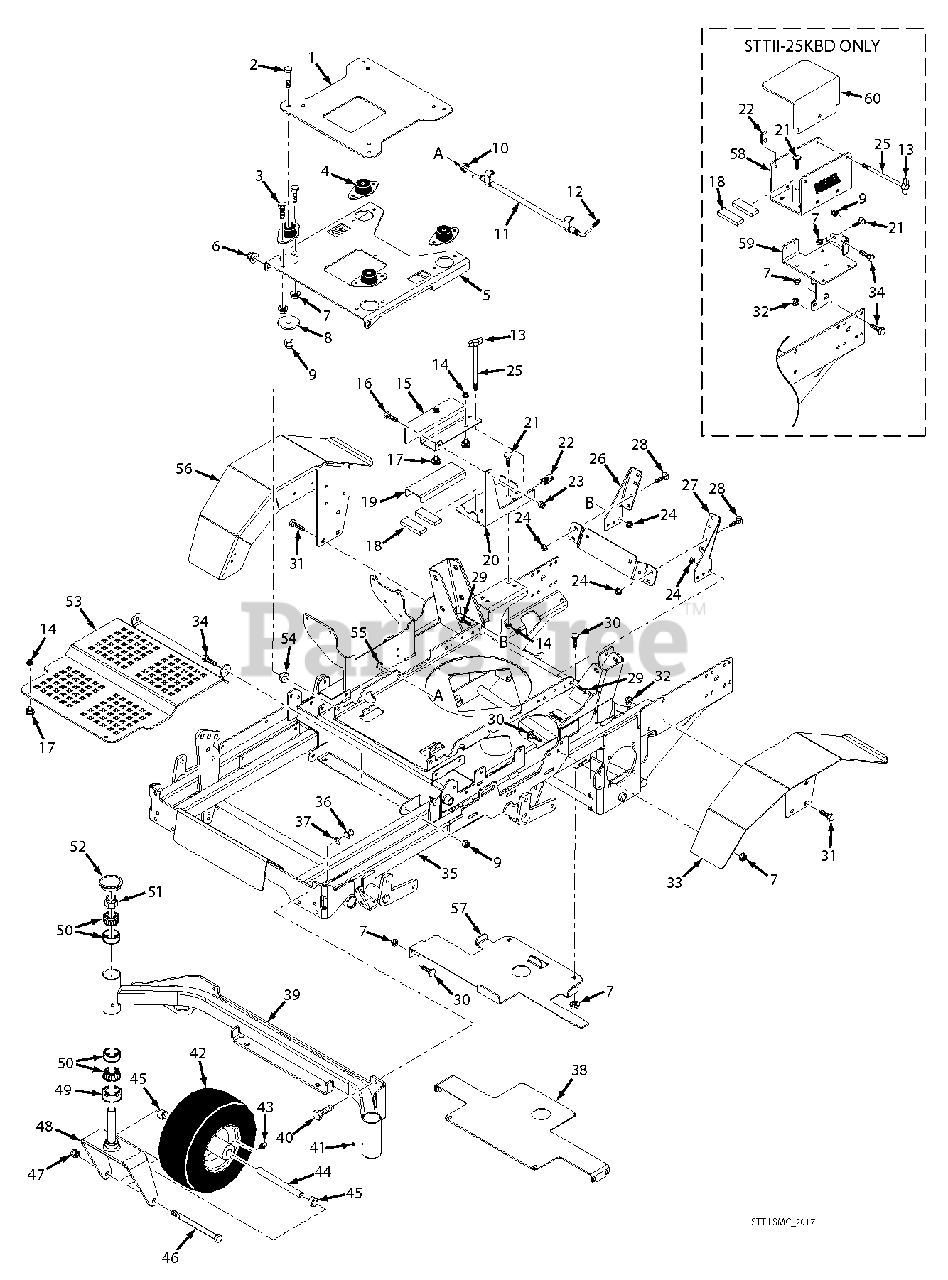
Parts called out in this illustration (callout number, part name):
1	Mounting Plate, Seat
2	Bolt, Hex Head 3/8-16 x 2-1/4"
3	Bolt, Hex Head 5/16-18 x 3/4"
4	Isolator, Seat
5	Seat Mounting Plate, Lower w/Decals
6	Nut, Flange Elastic Stop Nut, 3/8-16
7	Nut, Serrated Flange 5/16-18
8	Flatwasher, 3/8-.406 x 2.25 x .1875
9	Nut, Elastic Stop 3/8-16
10	Spring, Seat Latch
11	Lever Assy., Seat Release
13	Knob, 1/4" Wing
14	Nut, Serrated Flange 5/16-18
15	Cover, Battery Box (Gas Only)
16	Bolt, Hex Head 5/16-18 x 3/4"
17	Bumper, Rubber
18	Pad, Rubber
19	Insulation, Battery Cover (Gas Only)
20	Battery Box (Gas Only)
21	Bolt, Carriage 5/16-18 x 3/4"
22	U-Nut, 1/4-20
23	Nut, Elastic Stop 5/16-18
24	Nut, Serrated Flange 1/4-20
25	Bolt, Hex Head 1/4-20 x 8"
26	Mounting Bracket, Cooler - RH
27	Mounting Bracket, Cooler - LH
28	Bolt, Carriage 1/4-20 x 3/4"
29	Bolt, Hex Head 5/16-18 x 3/4"
30	Bolt, Carriage 5/16-18 x 3/4"
31	Bolt, Hex Head Serrated Flange 3/8-16 x 1"
32	Nut, Serrated Flange 3/8-16
33	Fender, LH
34	Bolt, Hex Head 3/8-16 x 1"
35	Mainframe Assy., w/Decals
36	Nut, Elastic Stop 7/16-14
37	Lockwasher, 7/16"
38	Front Support, Fuel Tank
39	Caster Support Weldment - 52V
39	Caster Support Weldment - 61V
39	Caster Support Weldment - 72V
40	Bolt, Hex Head 7/16-14 x 1-1/4"
41	Plug, Grease Hole
42	Wheel Assembly
42	Bearing
43	Grease Fitting
44	Sleeve, Caster Wheel
45	Spacer, Caster Wheel
46	Bolt, Hex Head 1/2-13 x 9-1/2"
47	Nut, Elastic Stop 1/2-13
48	Yoke Weldment
49	Seal, 2" O.D. x 1.625 Bore
50	Bearing Assembly
51	Nut, Jam 1" - 14
52	Cap, Grease
53	Foot Plate
54	Sleeve, Seat Base Mounting
55	Retaining Ring, .625 Ext. "E"
56	Fender, RH
57	Rear Support, Fuel Tank
58	Battery Box w/Decal (Diesel Only)
59	Battery Bracket Weldment (Diesel Only)
60	Cover, Battery (Diesel Only)
